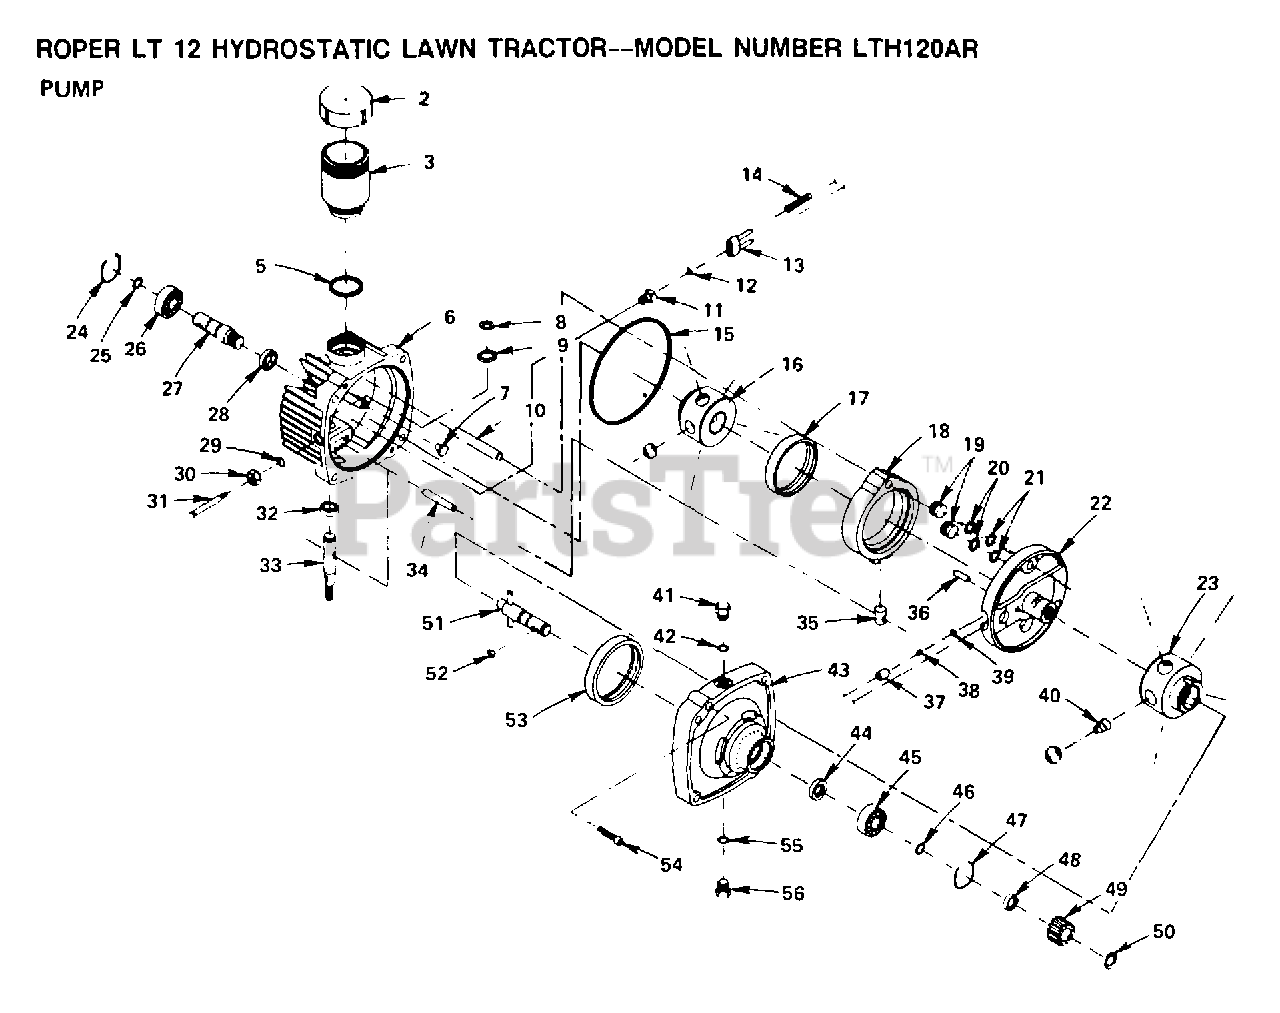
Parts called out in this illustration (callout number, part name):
2	RESERVOIR CVR HYT
3	RESERVOIR BDY HYT
5	SEAL RING HYT
8	RETAINING RING
11	GUIDE FITTING HYT
15	SEAL RING HYT
16	PUMP ROTOR HYT
17	PUMP RACE HYT
19	PISTON HYT
27	INPUT SHAFT HYT
29	O RING HYT
30	NUT&GASKET AS HYT
31	SHAFT DUMP HYT
33	CONTROL SHAFT
37	VALVE BODY HYT
39	RETAINER RING HYT
45	"HYT, BEARING"
47	RETAINER RING HYT
50	RETAINER RING HYT
51	OUTPUT SHAFT
52	KEY HYT
53	MOTOR RACE HYT
54	CAP SCREW HYT
